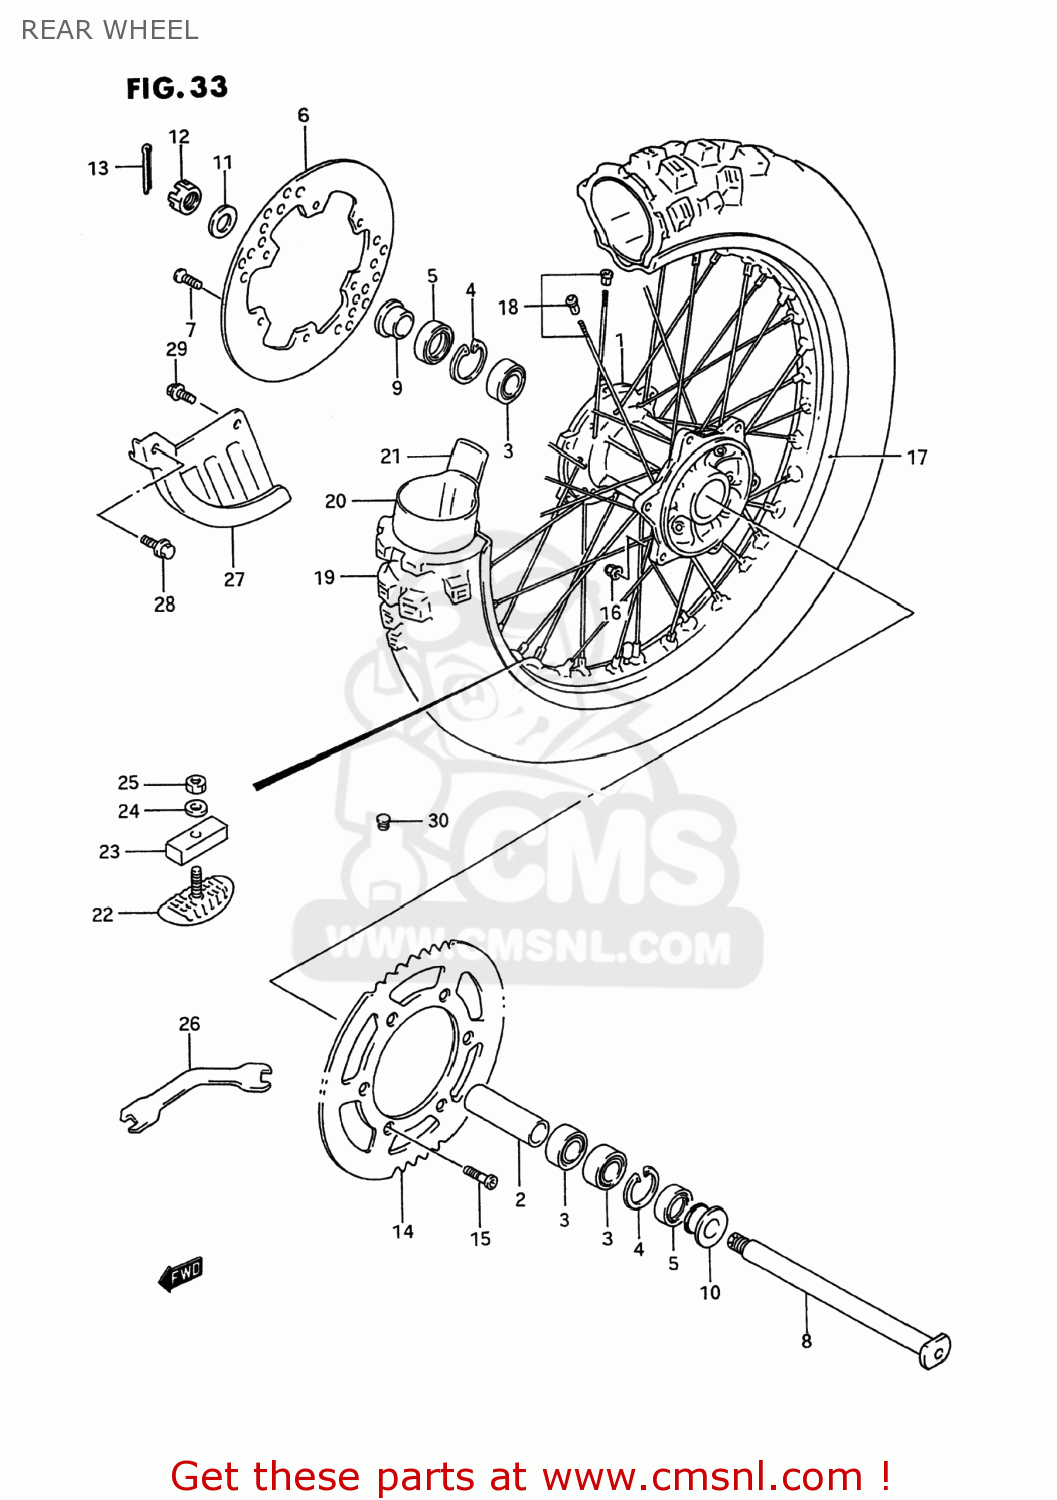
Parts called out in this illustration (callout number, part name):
1	HUB,RR WHEEL
2	SPACER,RR HUB BEARING
3	BEARING
4	CIRCLIP
5	SEAL(29X42X6)
6	DISC,RR BRAKE
7	SCREW,BRAKE DISC
8	AXLE,RR
9	SPACER,RR AXLE,R
10	SPACER,RR AXLE
11	WASHER(19X32X3.2)
12	NUT
13	PIN,COTTER
14	SPROCKET,REAR
15	BOLT(8X30.5)
16	NUT
17	RIM,RR WHEEL(2.15X19 AL)
18	SPOKE SET,RR WHEEL
19	TIRE
20	TUBE ASSY,WHEEL INNER
21	PROTECTOR,WHL INR TUBE
22	STOPPER,BEAD(2.15)
23	CUSHION,BEAD STOPPER
24	WASHER
25	NUT
26	SPANNER,OPEN
27	COVER,REAR DISC
28	BOLT
29	BOLT
30	CAP(OD:12)
